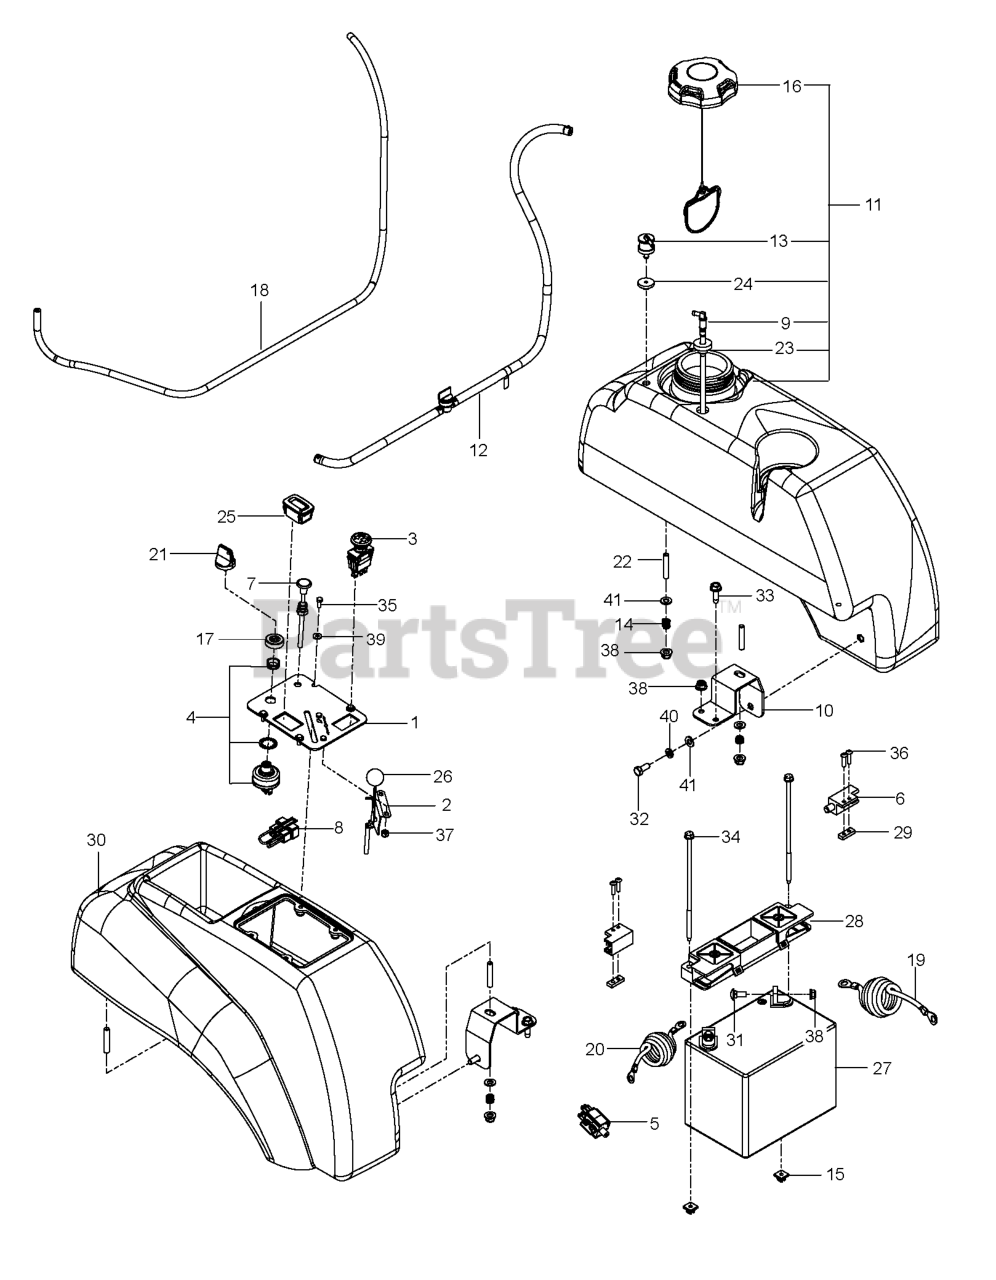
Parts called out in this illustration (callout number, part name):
1	PLATE.CONSOLE.BLACK
2	THROTTLE CABLE
3	RP SWITCH.PTO.TERMINAL.STD.RED
4	SWITCH, IGNITION, INDAK
5	SWITCH, BRAKE 3P
6	SWITCH, INTERLOCK
7	CABLE, CHOKE, 38
8	PLUG, TIMER
9	FITTING, FUEL
10	SUPPORT, TANK, BLK
11	FUEL.TANK.ASSY.LH.MZ.GRY
12	FUEL.HOSE.SHUT.OFF.ASM.26".10"
13	VALVE.FUEL.CHECK
15	PUSH NUT-NYLON
16	CAP, FUEL
17	CAP IGNITION NUT
18	HOSE, VAPOR 3/16 X 48"
19	POST.CABLE LONG
20	NEG. CABLE, 28"
21	KEY, IGNITION
22	STUD, 5/16C
23	RUBBER GROMMET
24	GROMMET, CHECK VALVE
25	GUAGE.SRVCMNDR.HRMTR.
26	KNOB.ROUND.BALL.BLACK
27	BATTERY, 12 V 300 AMP DRY
28	BATTERY HOLD DOWN
29	TAPPED PLATE
30	FENDER CONSOLE
31	BOLT 5/16C X 3/4" CARRIAGE
32	HCS 5/16C X 3/4
33	RP BLT 5/16-18 X 1 THRD FORM D
34	BOLT - 1/4-20 X 7.5
35	HCS #10-24 X 1/2
36	SCR #10-24 X .75 SKT HD BLK
37	NUT 10-24 NYLOC
38	5/16-18 NYLOC FLANGE NUT
40	WASH.5/16.SLW.ZD
41	WASHER
